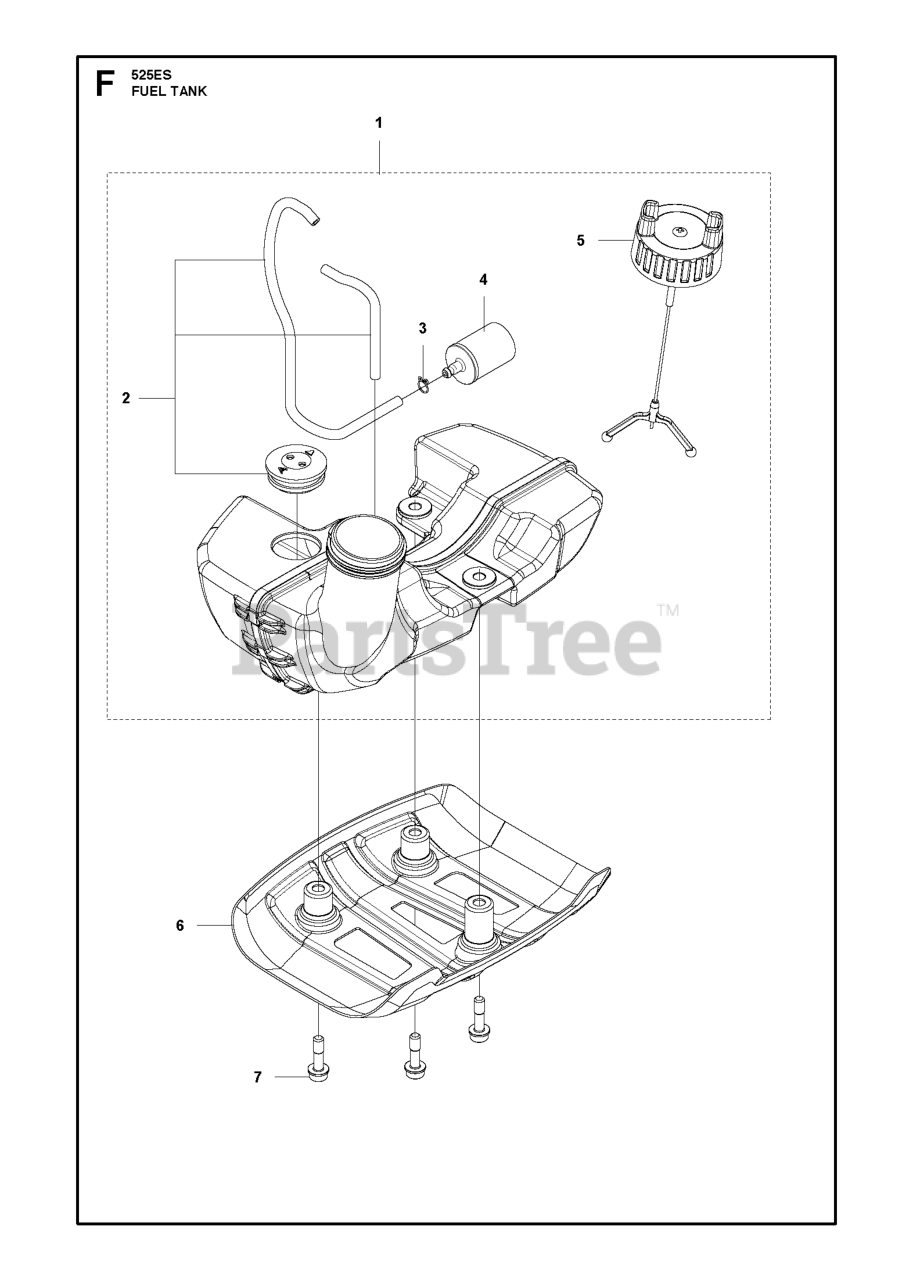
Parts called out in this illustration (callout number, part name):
1	Fuel Tanks
2	Fuel Hoses
4	RP FUEL FILTER
6	SKID PLATE
7	BOLT
